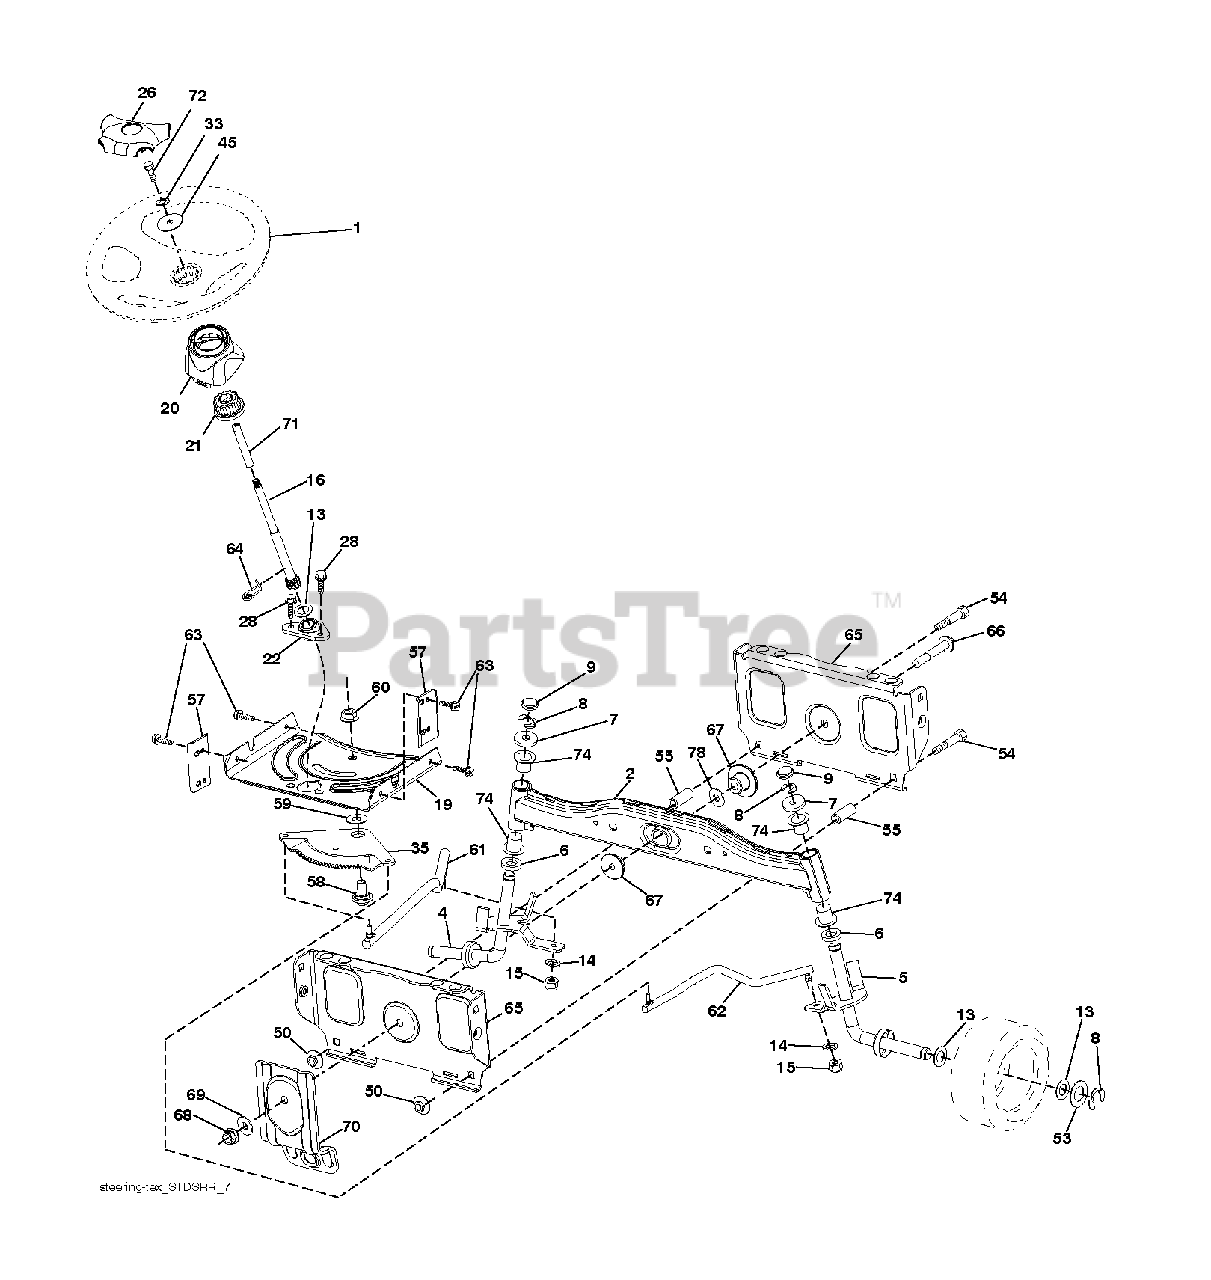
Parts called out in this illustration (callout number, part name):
1	WHEEL.STEERING.STDSRR.BLK/OV
2	AXLE HALF ASM-WELDED
4	SPINDLE.WELDED.LH.15"TEX
5	SPINDLE.WELDED.RH.15"T
8	RING CLIP
9	CAP.SPINDLE
14	WASHER, LOCK 3/8
15	NUT CROWNLOCK 3/8-24
16	SHAFT STEERING
19	PLATE.STEER.DDL.NLT/NG
20	BOOT.STEERING.PREDATOR.LT.BLAC
21	ADAPTER, WHEEL STNG..
22	BUSHING.ASM.STEERING.A
26	CAP.WHL.STRNG.STDSRRD.SRS.BLK
28	SCREW, 3/8-16X3/4
33	LOCKWASHER
35	GEAR.SECTOR.PLATE.DDL.
45	WASHER.11/32
50	NUT LOCK FLG 3/8-16 UNC
53	WASHER.HARDENED
55	SPACER.BRACE.AXLE
57	BRACKET.UPSTOP.TEX
58	BOLT.SHOULDER.SECTOR.P
59	WASHER.THURST.SECTOR.S
60	NUT FLANGE LOCK 5/8-11
61	DRAGLINK.LH.BALLSTUD.D
62	DRAGLINK.RH.BALLSTUD.D
63	SCREW
64	RETAINER.CLIP.SPRING.S
65	BRACE.AXLE.FRONT.NLT/N
66	BOLT HEX FGHD 7/16-14 X 3 SERR
67	BUSHING.PM.FRONT AXLE
68	NUT.LOCK.FLANGE.7/16
69	WASHER.1.5X.505X.118
70	BRKT.DECK.SUSPENSION.F
71	SHAFT EXTENSION STEERING
72	BOLT YT
74	BRNG T
78	THRUST WASHER
